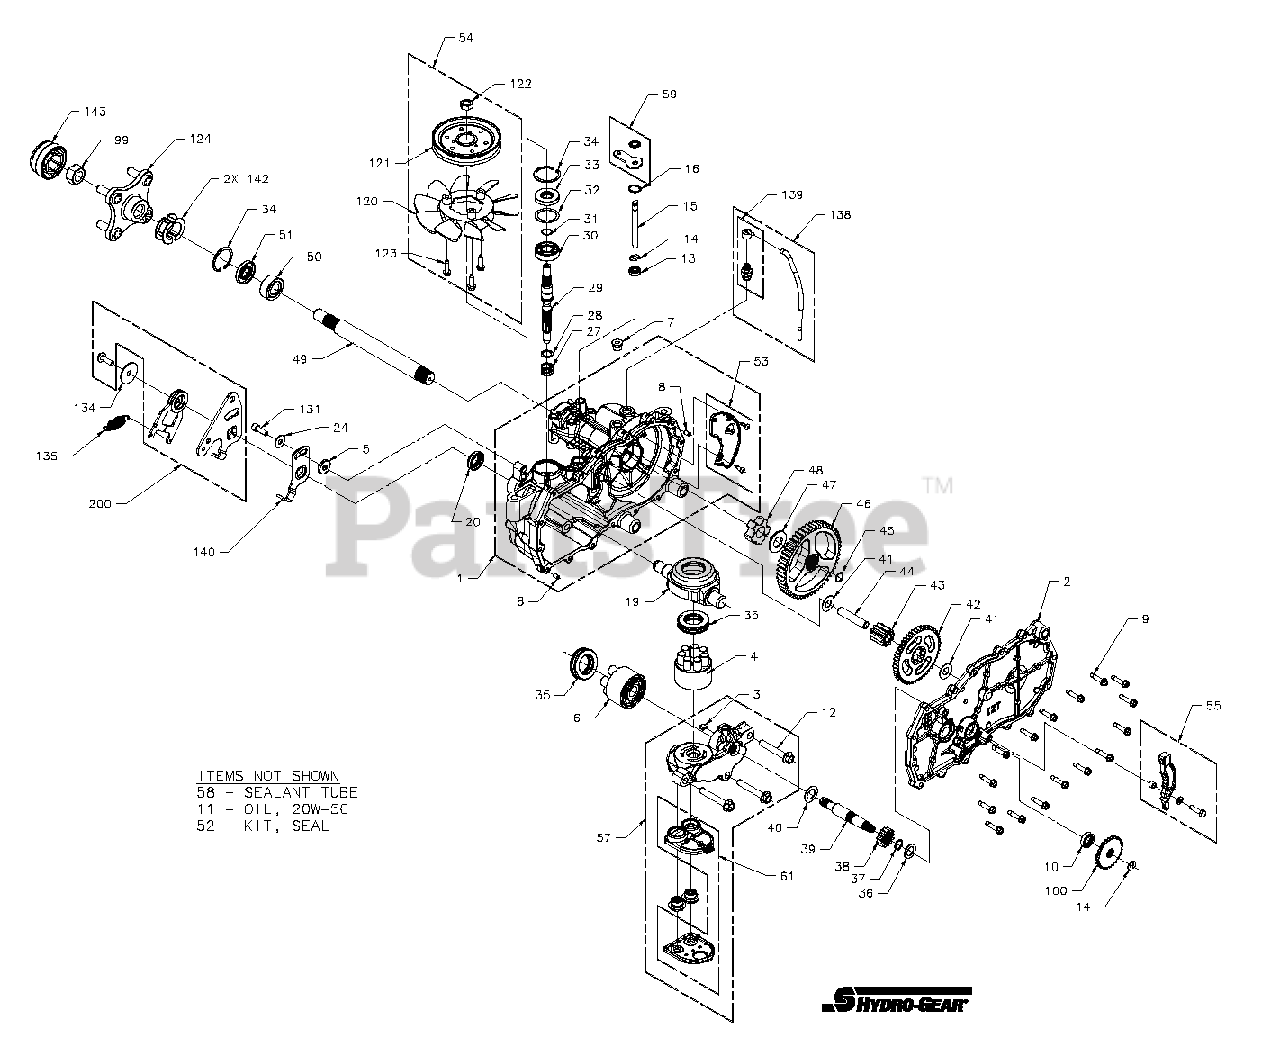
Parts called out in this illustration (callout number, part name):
1	ASSEMBLY, MAIN HOUSING - LH
4	ASSEMBLY, PUMP BLOCK (7P-10CC)
6	ASSEMBLY, MOTOR BLOCK (5P-10CC)
10	KIT, BRAKE SEAL
13	SEAL, LIP .375 X .75 X .25
14	RING, RETAINING .375 EXT
19	SWASHPLATE, TRUNNION, MACHINED
20	SEAL, LIP 18 X 32 X 7
28	WASHER .591 X .787 X .040
29	SHAFT, INPUT
30	BEARING, BALL 17MM ID X 40 MM OD X 12 MM
33	SEDAL, LIP 17 X 40 X 7
34	RING, RETAINING
35	BEARING, THRUST 30 X 52 X 13
41	WASHER HT .5 ID X 1.0 OD X .032
45	RING, SPIRAL RETAINING
50	BUSHING, AXLE
51	SEAL, LIP .75 X 1.5
52	KIT, SEAL
55	KIT, BRAKE ARM
58	SEALANT TUBE, 10.3 OZ
99	NUT, HEX 3/4-16
100	DISC, COG BRAKE
121	PULLEY 4/5 X 1.625
124	KIT, HUB 1/2-20
134	WASHER 1.5 X .34 X .062
135	SPRING, EXTENSION
